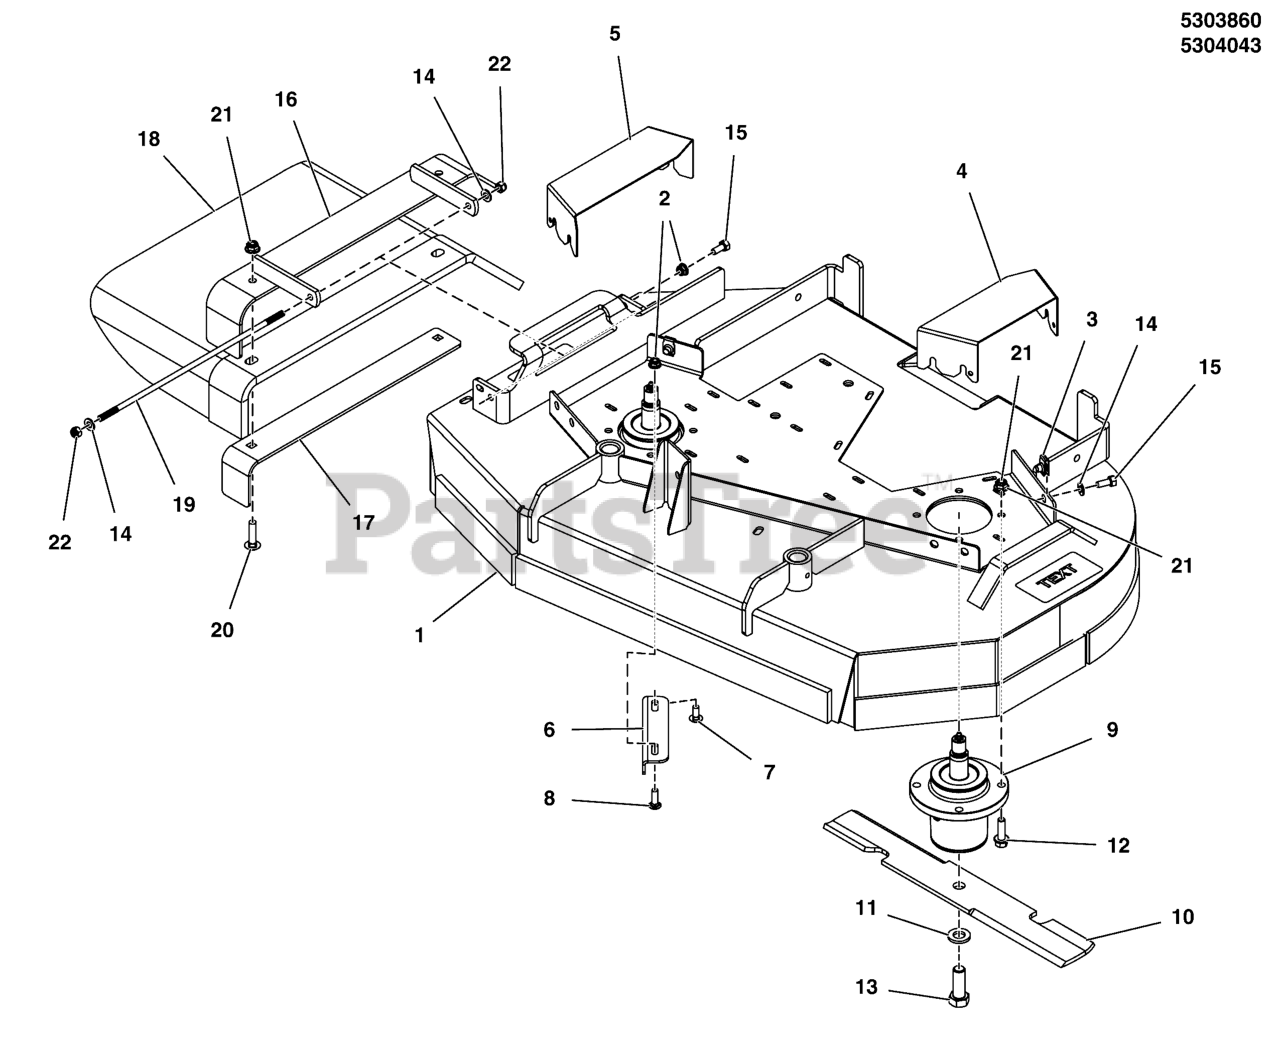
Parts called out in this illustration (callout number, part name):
1	DECK SHELL W/DECALS, SW25-36 (5415679D)
2	NUT, 5/16-18 HEX NYLOCK FLANGE NUT
3	BODY CLIP, 5/16-18-7GA MATERIAL
4	GUARD, DECK, LH, W25 36 - RED
5	GUARD, DECK, RH, W25 36 - RED
6	PLATE, DEFLECTOR, 36" - BLK
7	BOLT, 5/16-18 X 3/4, CARRIAGE, GD5, CZ
8	BOLT, 5/16-18 X 1, CARRIAGE, GD5, CZ
9	SPINDLE, ASSM, ALUMINUM - 5.25
10	BLADE SET, 36 DECK (2)
11	WASHER, BLADE BOLT, 9/16" F436, CZ
12	BOLT, 3/8-16 X 1-1/4, FLANGE, GD 5, CZ
13	BOLT, 5/8-11 X 1-3/4 GD8
14	WASHER, 5/16" SAE
15	BOLT, 5/16-18 X 3/4 GD5
16	WELD, MOUNT, DISCHARGE CHUTE - BLK
17	SUPPORT, DISCHARGE CHUTE - BLK
18	CHUTE, RUBBER DISCHARGE CHUTE (5104441)
19	ROD, 5/16 X 13.75, TBE, CZ
20	BOLT, 3/8-16 X 1-1/2, CARRIAGE, GD5, CZ
21	NUT, 3/8 - 16 HEX NYLOCK FLANGE
22	NUT, 5/16-24 HEX NYLON LOCK
